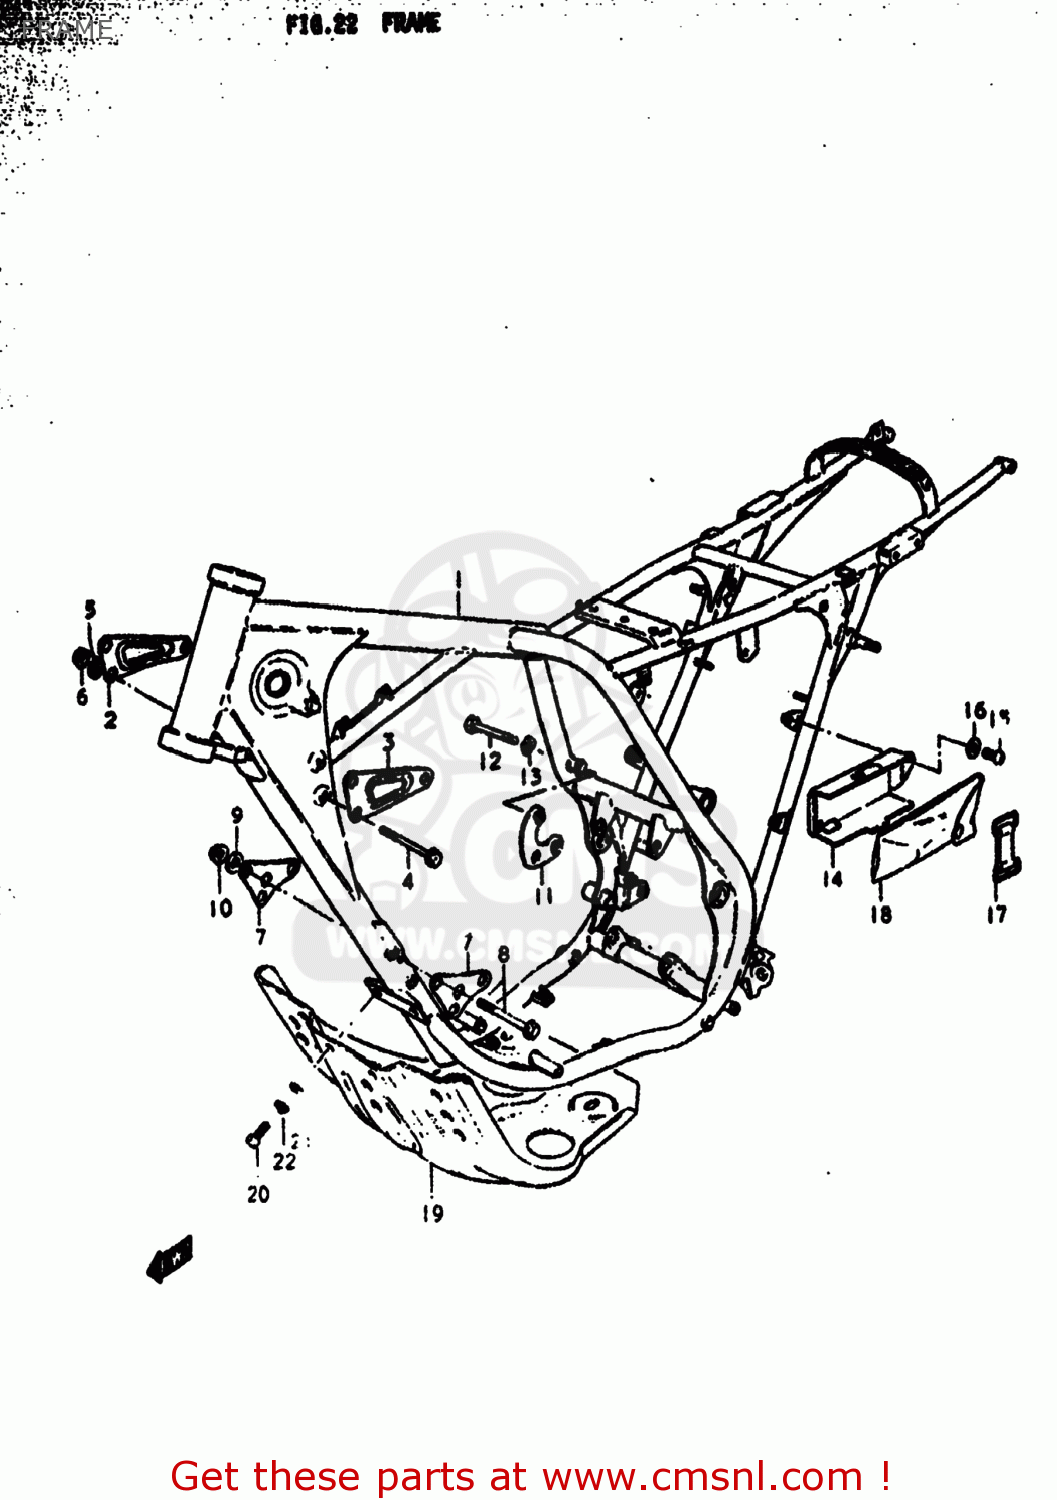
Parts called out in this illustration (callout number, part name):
1	FRAME
2	PLATE,ENGINE MOUNTING
3	PLATE,ENGINE MOUNTING
4	BOLT (6X70)
5	WASHER
6	NUT
7	PLATE,ENGINE MOUNTING
8	BOLT (8X70)
9	WASHER
10	NUT
11	PLATE,ENGINE MOUNTING
12	BOLT
13	LOCK WASHER
14	HOLDER,TOOL
15	SCREW
16	WASHER 6MM
17	BAND
18	TOOL SET
19	PROTECTOR,ENGINE
20	BOLT, UPPER
21	WASHER
22	LOCK WASHER
